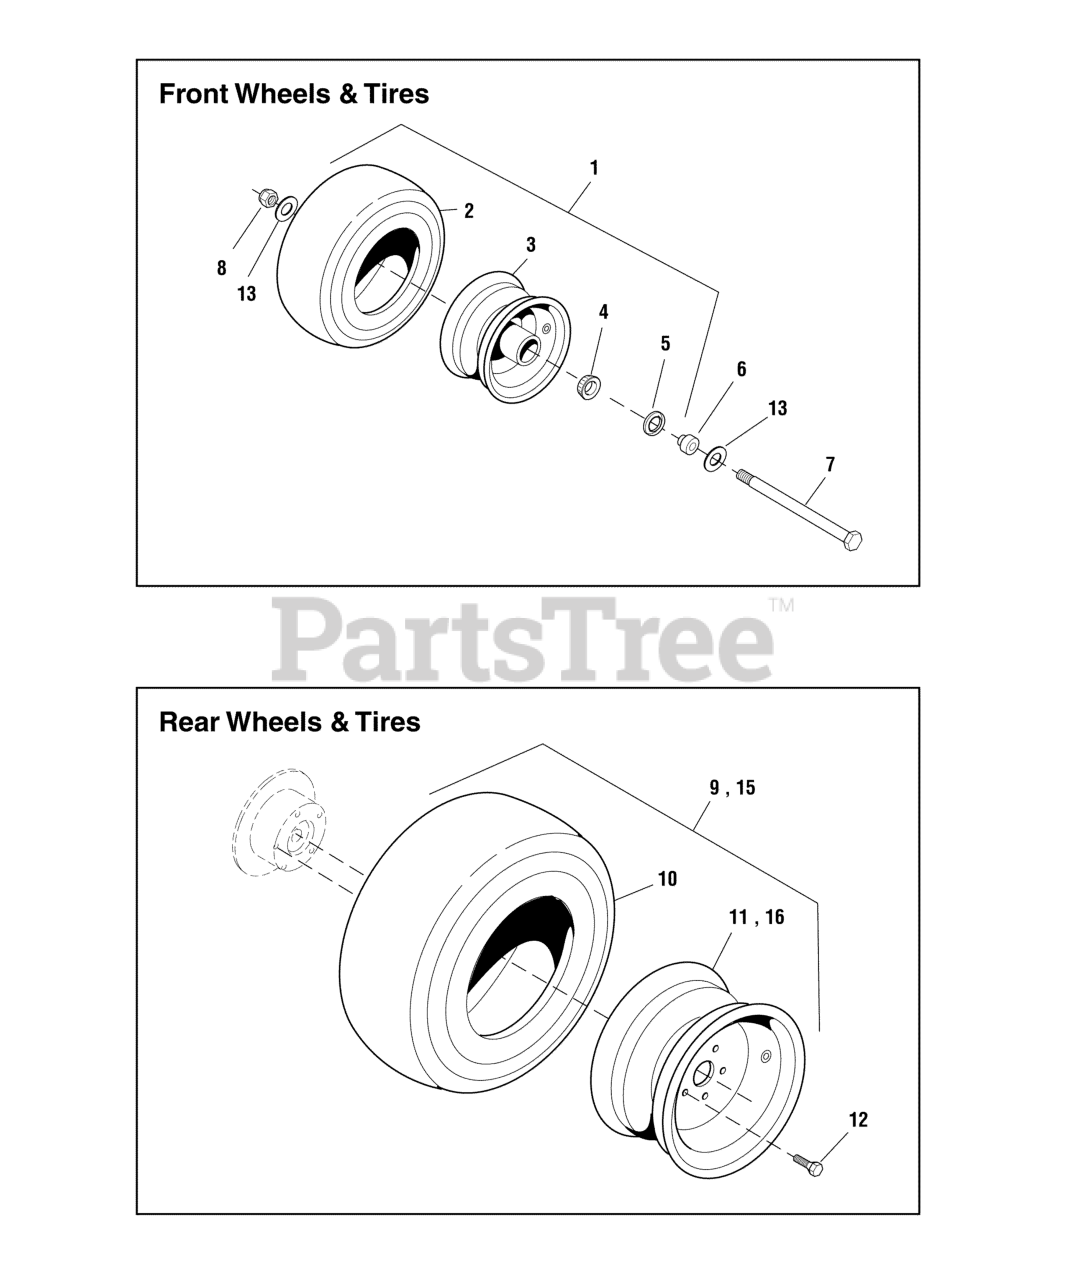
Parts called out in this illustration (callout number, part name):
1	TIRE ASSM, 13 X 6.5 - 6, PNE / TB
2	TIRE, RUBBER ONLY
3	WHEEL ASSEMBLY, for 13 x 6.5 x 6 Tires, Complete
4	BEARING, Tapered Roller
5	SEAL, GREASE
6	ADAPTER, CASTER AXLE, CZ
7	BOLT, 1/2-13 X 9" GD5 YZ
8	NUT, 1/2-13 HEX NYLON LOCK
9	TIRE ASSM, 26X12.00-12, SOLID
10	TIRE, 26 X 12 - 12
11	WHEEL, 12 X 8.5
12	BOLT, WHEEL LUG, 1/2" X 1-5/8
13	WASHER, 1/2 SAE
15	WHEEL/TIRE ASSY, 26X12-12, 4PLY K505
16	Wheel, 12 X 9.5", 5 Hole
